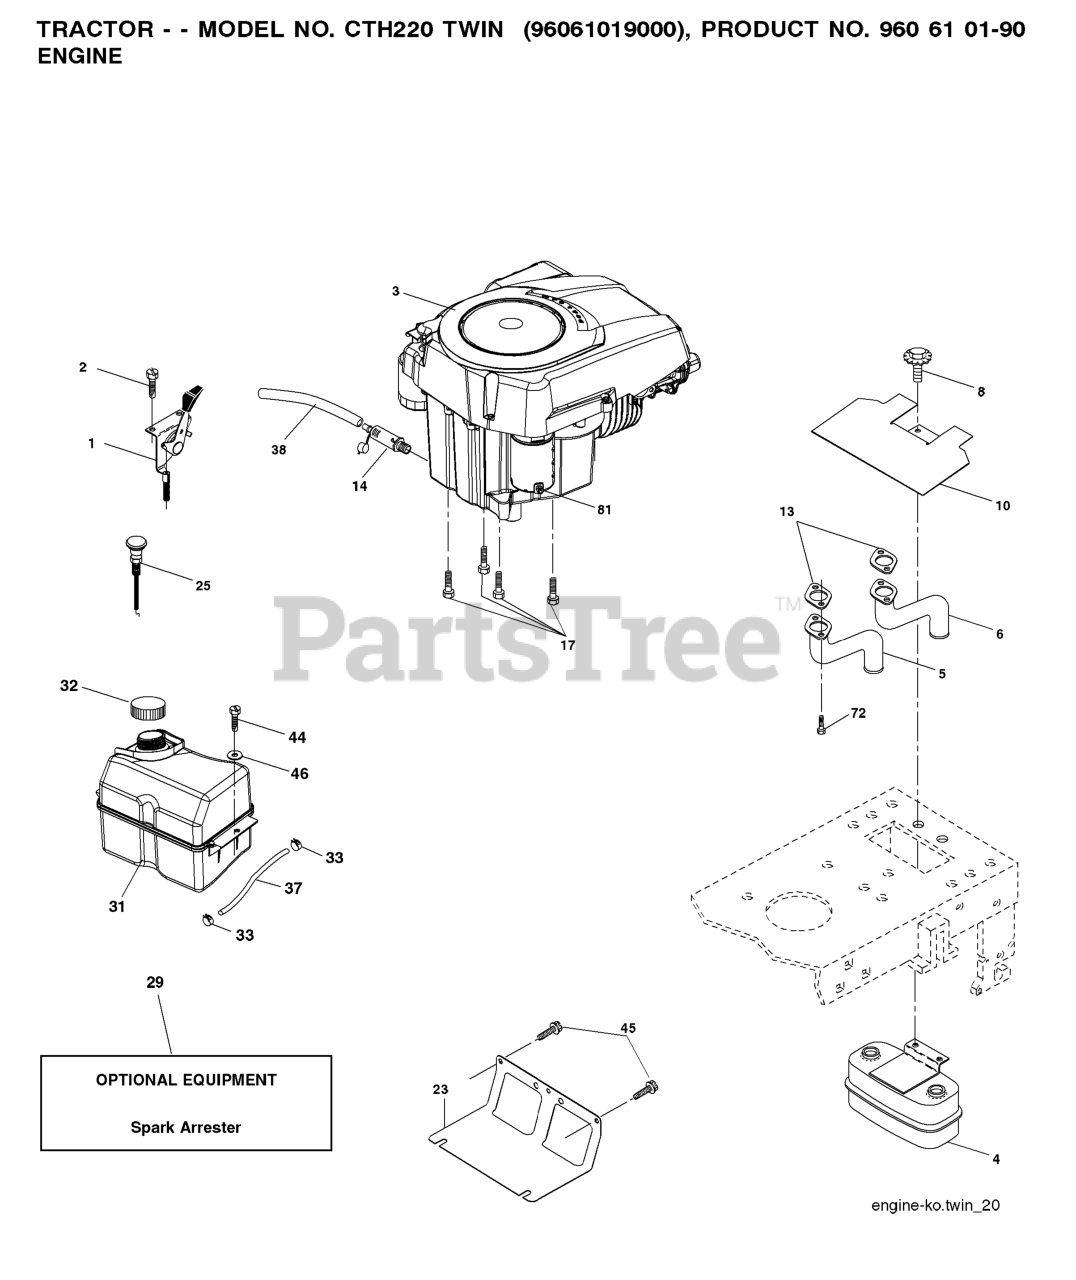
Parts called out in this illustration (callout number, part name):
1	THROTTLE CONTROL
2	SCREW
4	MUFFLER.TWIN.CYL.LOW.TONE
5	RP.PIPE-EXHAUST LH
6	RP.PIPE-EXHAUST RH
8	BOLT.5/16-18UNCX3/4 W/SEMS.BLK
10	RP SHIELD HEAT MUFFLER
14	TUBE, DRAIN OIL ASM.
17	SCREW 3/8-16X1
23	SHIELD.BROWNING.DBR.GUARD
25	CONTROL, CHOKE
29	KIT.SPARK ARRESTOR 794945 B&S
31	TANK FUEL
32	FUEL CAP
33	HOSE CLAMP
37	LINE.FUEL.20
38	PLUG DRAIN OIL EASY
44	SCREW HEXWSHR 1/4-20X3/4
45	SCREW, 3/8-16X3/4
46	WASHER
72	SCREW.SOCKET HD.5/16-1
81	NUT
